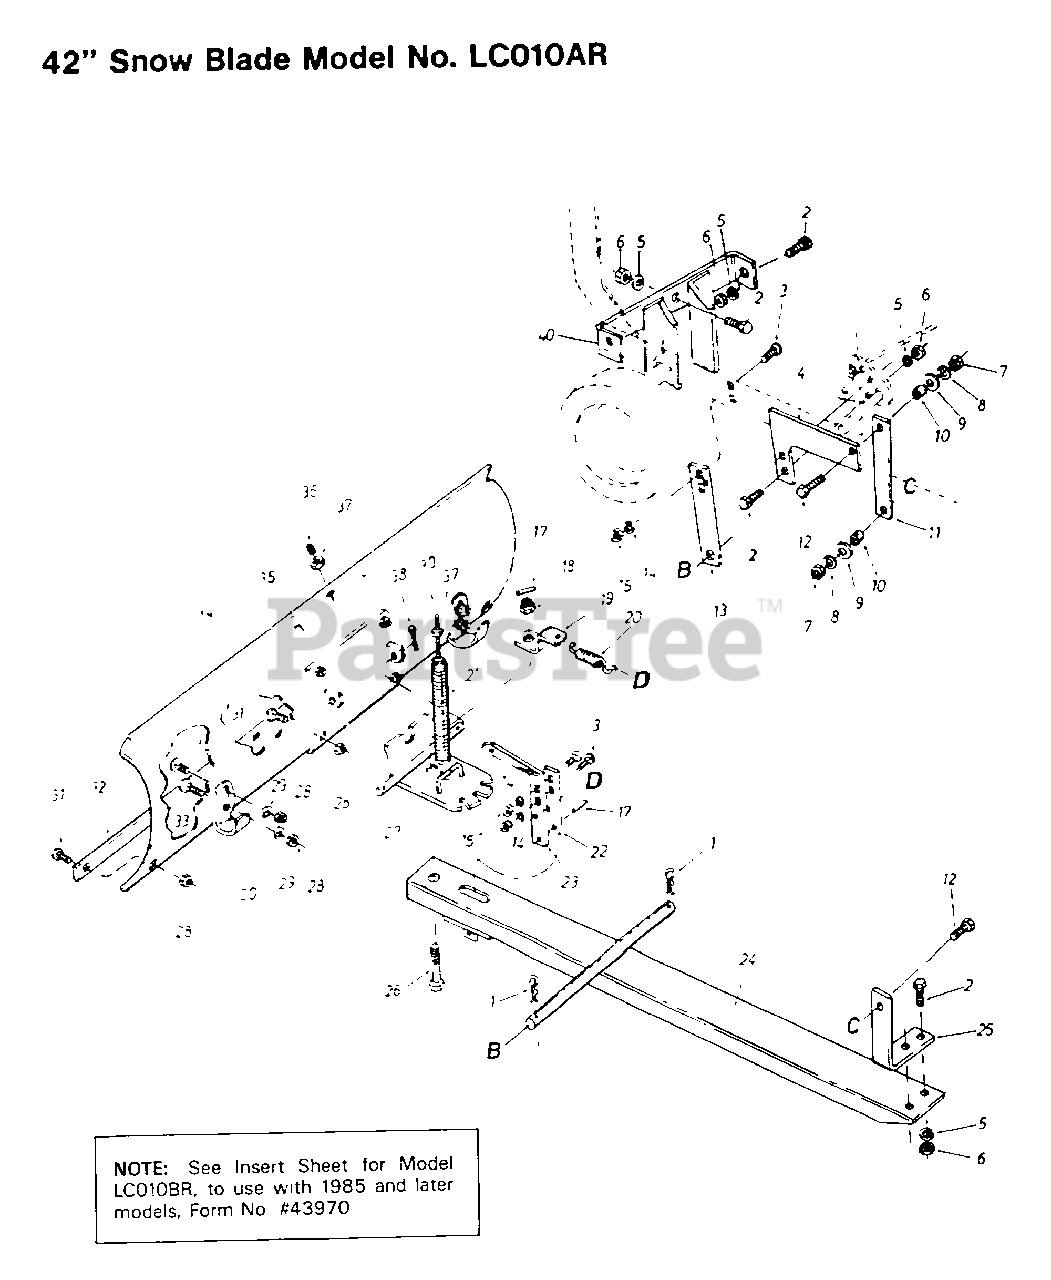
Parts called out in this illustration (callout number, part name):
1	HAIR PIN COTTER
10	PIVOT BUSHING
22	BAR ANGLE LO
24	CHANNEL ASSY
27	PIVOT PLATE ASSY
28	No Desciption for Part
40	GUIDE BRKT ASSY
